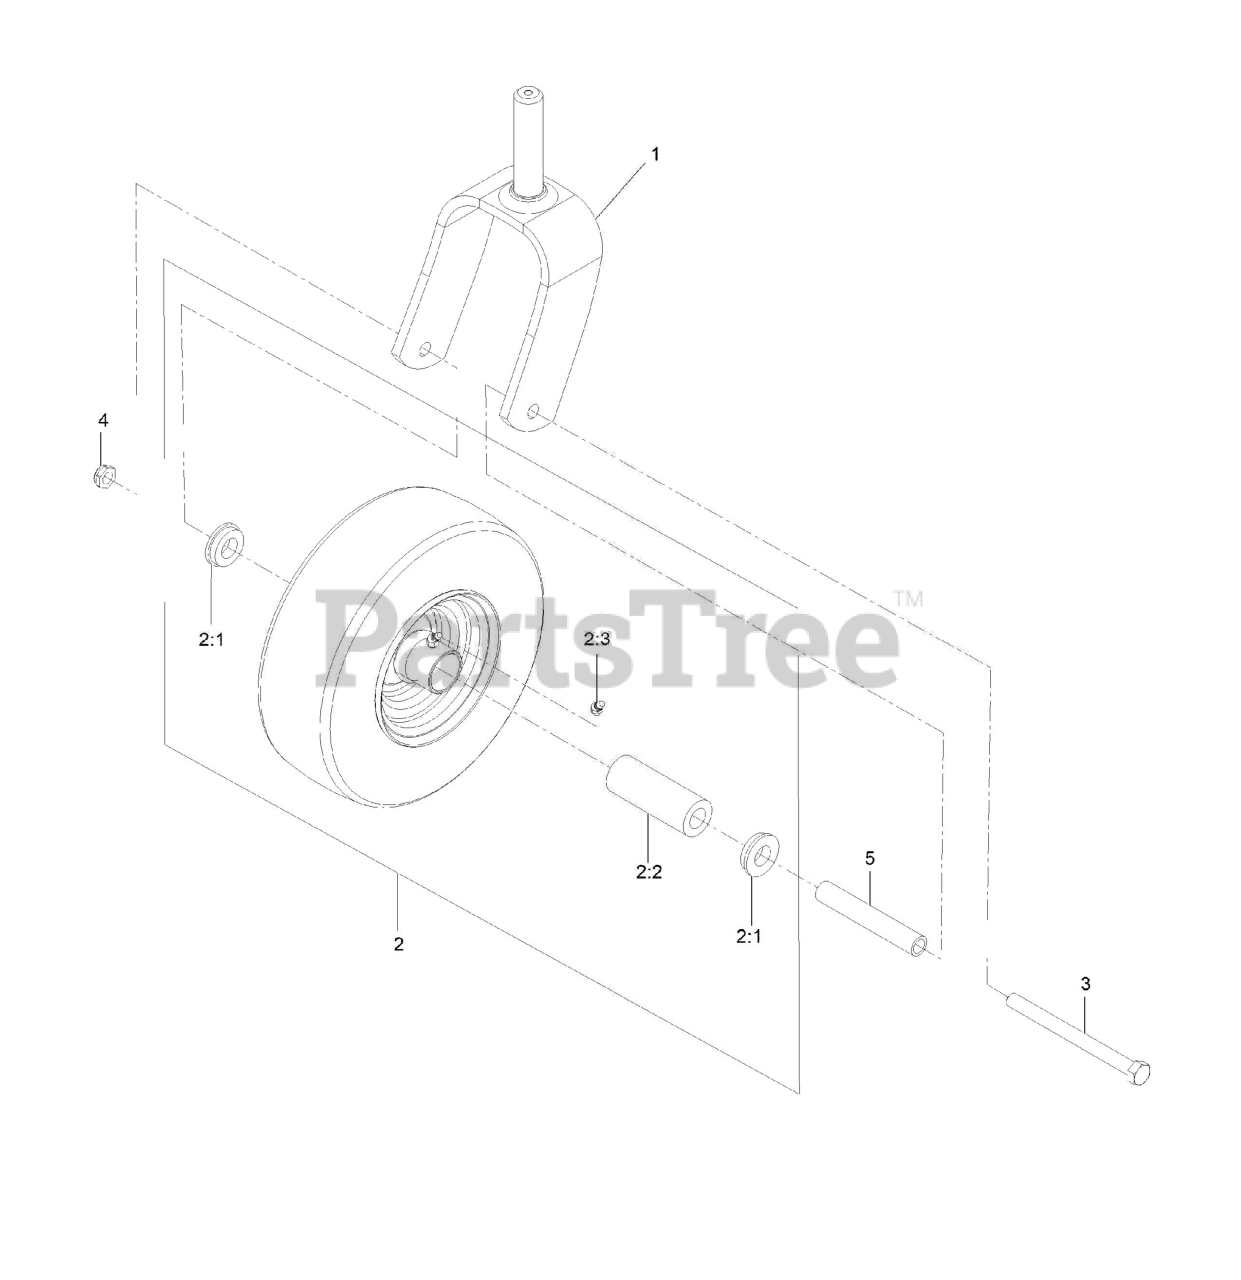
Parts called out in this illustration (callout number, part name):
1	FORK-CASTER
2	WHEEL AND TIRE ASM
2:1	BUSHING
2:2	BEARING
2:3	FITTING-GREASE
3	SCREW-HH
4	NUT-HEX
